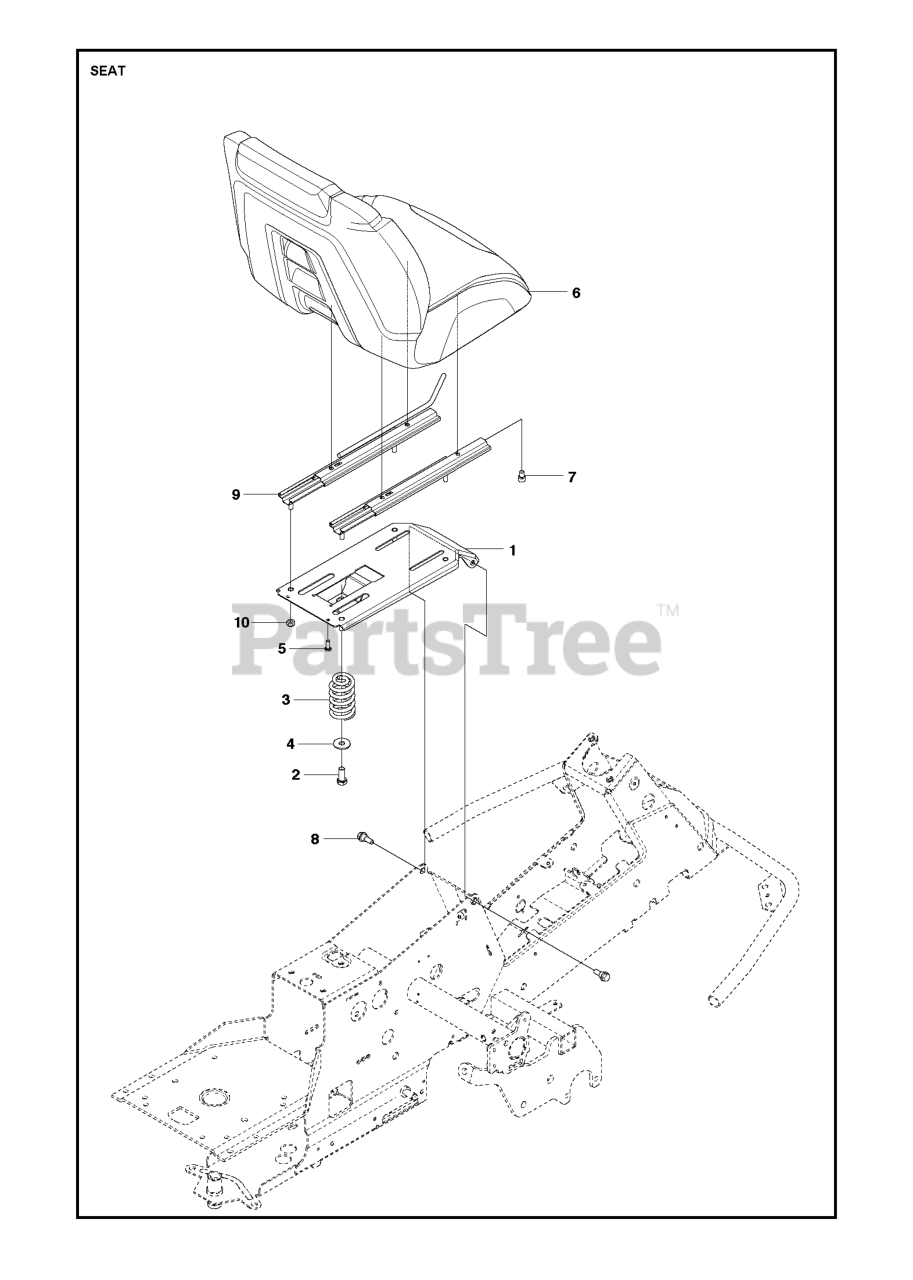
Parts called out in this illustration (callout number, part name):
1	SEAT BRACKET 300 ASSY GREY
2	Screw M10x25
3	SEAT SPRING
5	SCREW
6	SEAT HUSQVARNA HIGH BACK
7	SCREW IHSCM
9	SEAT ADJUSTER LEFT & RIGHT
10	LOCKNUT M8
